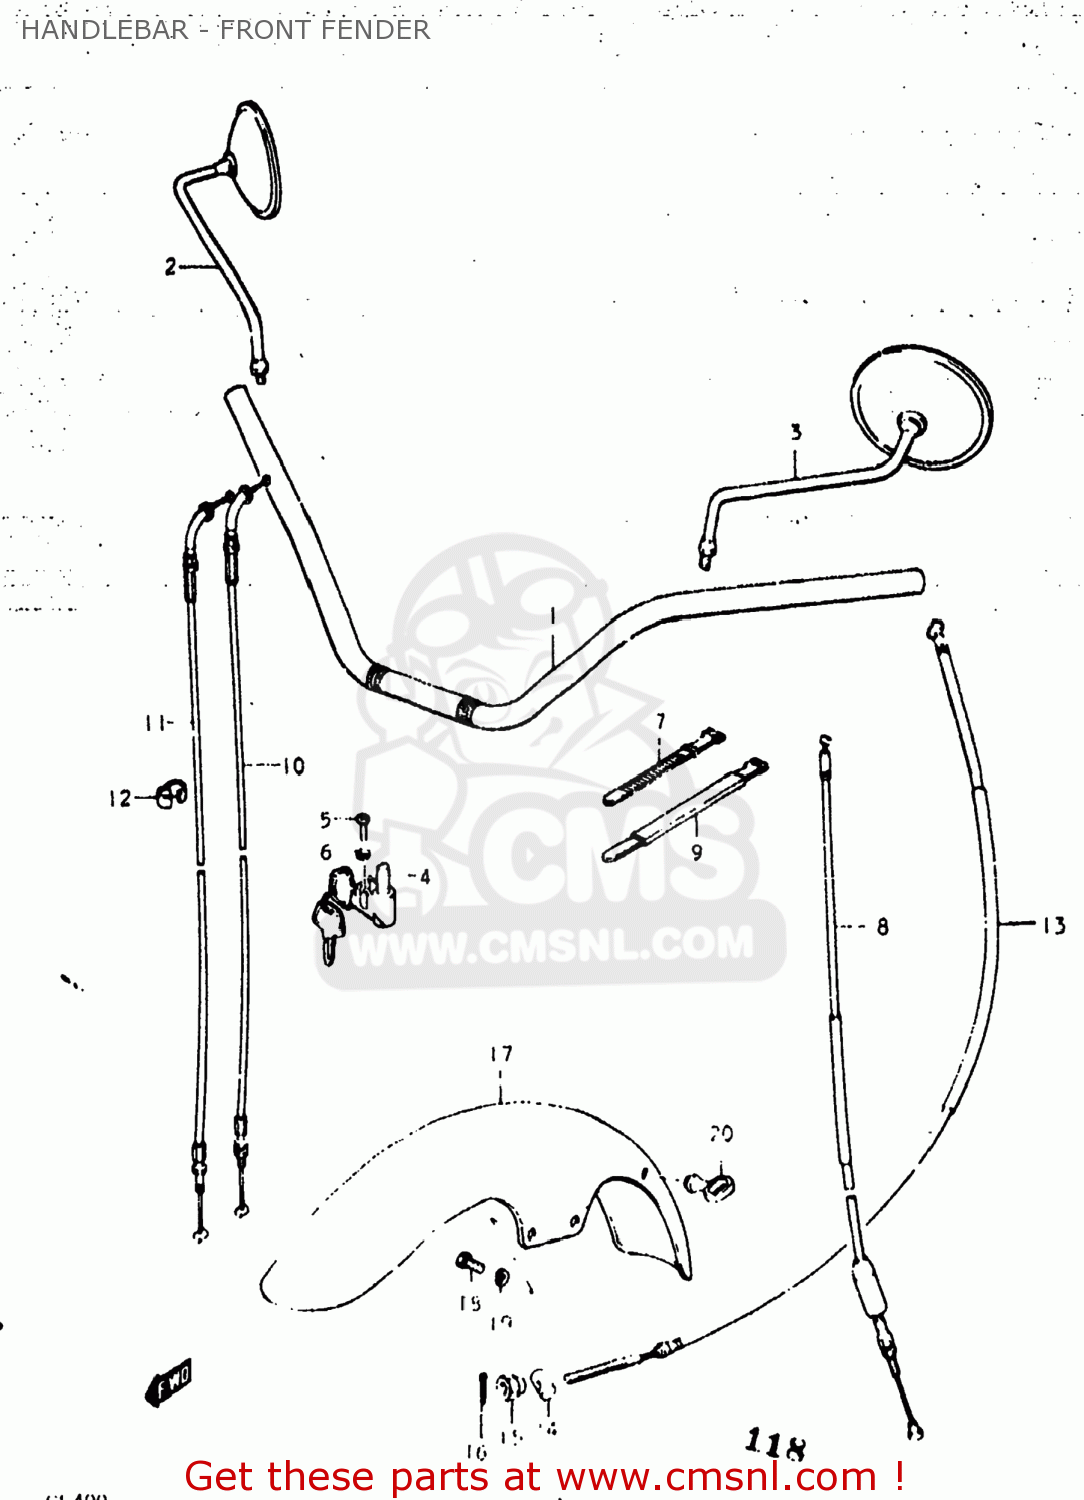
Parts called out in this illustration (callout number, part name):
1	HANDLEBAR,RIGHT
2	MIRROR ASSEMBLY,RIGHT
3	MIRROR ASSEMBLY,LEFT
4	LOCK ASSEMBLY,STEERING
5	SCREW
6	LOCK WASHER
7	CLAMP(L:120)
8	CABLE ASSEMBLY,CLUTCH
9	CLAMP
10	CABLE ASSY,THROTTLE NO.1
11	CABLE ASSY,THROTTLE NO.2
12	CLIP
13	CABLE ASSEMBLY,FRONT BRAKE
14	PIN
15	NUT
16	PIN
17	FENDER,FRONT
18	BOLT
19	LOCK WASHER
20	GUIDE,CABLE
